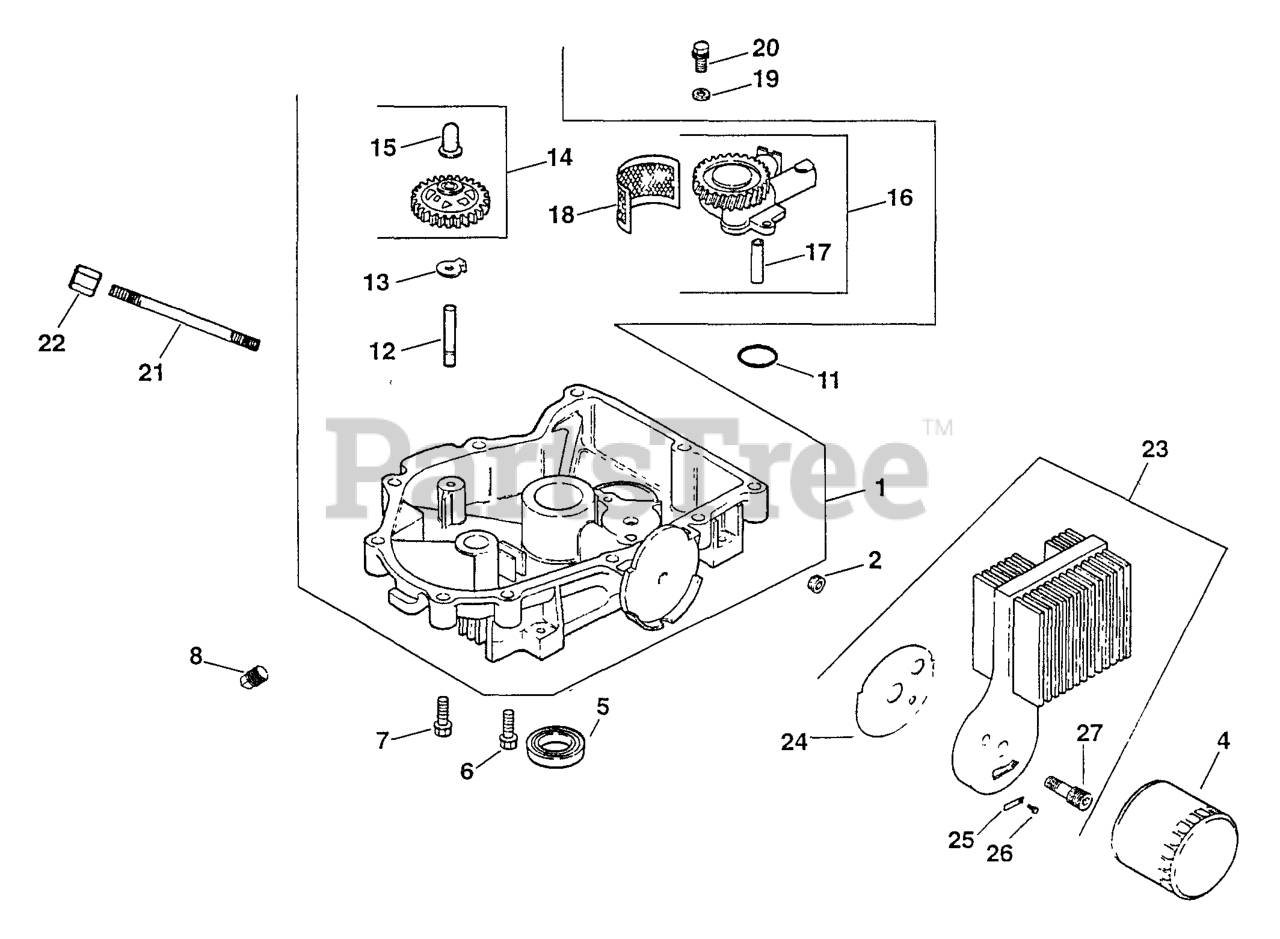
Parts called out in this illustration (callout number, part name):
1	PAN , OIL ASSEMBLY USE 24 199 32-S
2	PLUG, PIPE CTSK 3/8" USE 25 139 62-S
4	OIL FILTER
5	SEAL, OIL (KM)-USE 25 032 06-S
6	SCREW, FLG M8X1.25X45
7	SCREW, HEX FLANGE -USE 24 086 17-S
12	SHAFT, GOVERNOR GEAR
14	KIT, GOVERNOR GEAR W/PIN
15	PIN, GOVERNOR REGULATING
16	PUMP, OIL-DISCONTINUED
18	SCREEN - USE 25 162 07
19	WASHER - USE M-631005
20	SCREW - USE M-645025
21	NIPPLE - USE 12 136 11
22	CAP, PIPE
